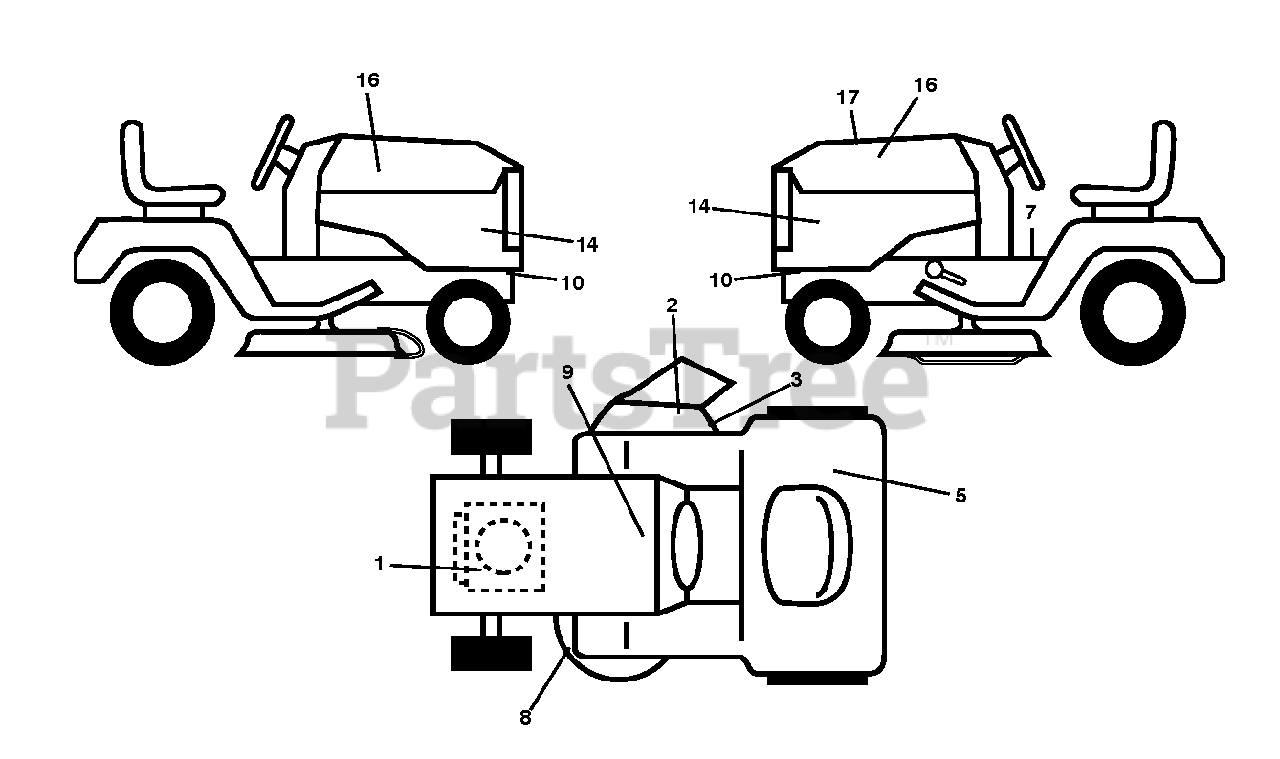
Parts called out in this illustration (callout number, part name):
1	DECAL.ENGINE.WARNING
2	DECAL, DECK DEFLECTOR, WARNING
3	DECAL.DFLCTR.WARNNG.CTFNGR.SYM
5	DECAL CERTIFICATION DECAL EMCC
7	Decal, Tractor Saddle
8	DECAL.V-BELT.SCH.42/46"MEC/ELE
9	DECAL BTRY SYMBOLS
10	DECAL.CHASSIS.HOT.MUFFLER
14	DECAL.SDPNL.HUSQGT.TS246.RH/LH
16	DECAL.BADGE.170MM.TEXTLOGO.
17	Decal, Replacement Kawasaki FR TLW
